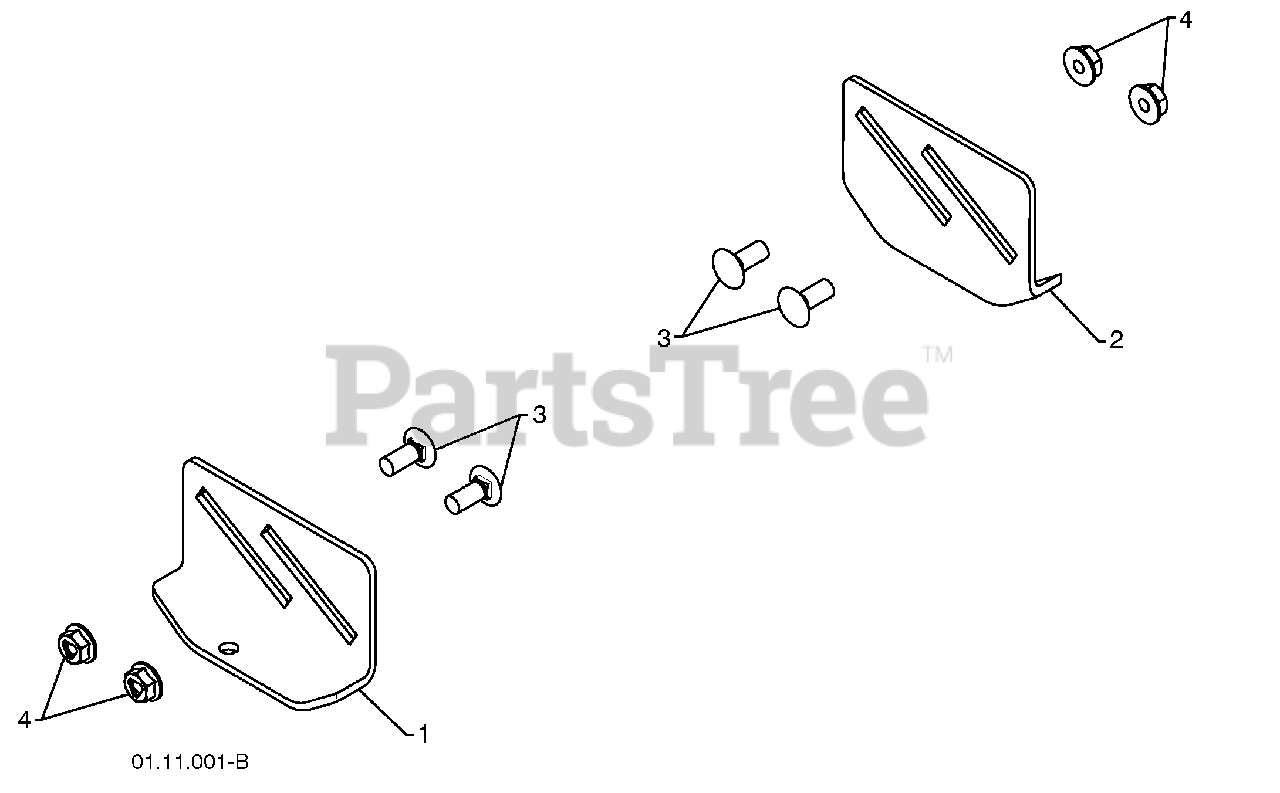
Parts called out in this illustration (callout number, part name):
1	SKID PLATE LH
2	SKID PLATE RH
3	CARRIAGE BOLT 5/16-18 X .75
4	NUT 5/16-18
